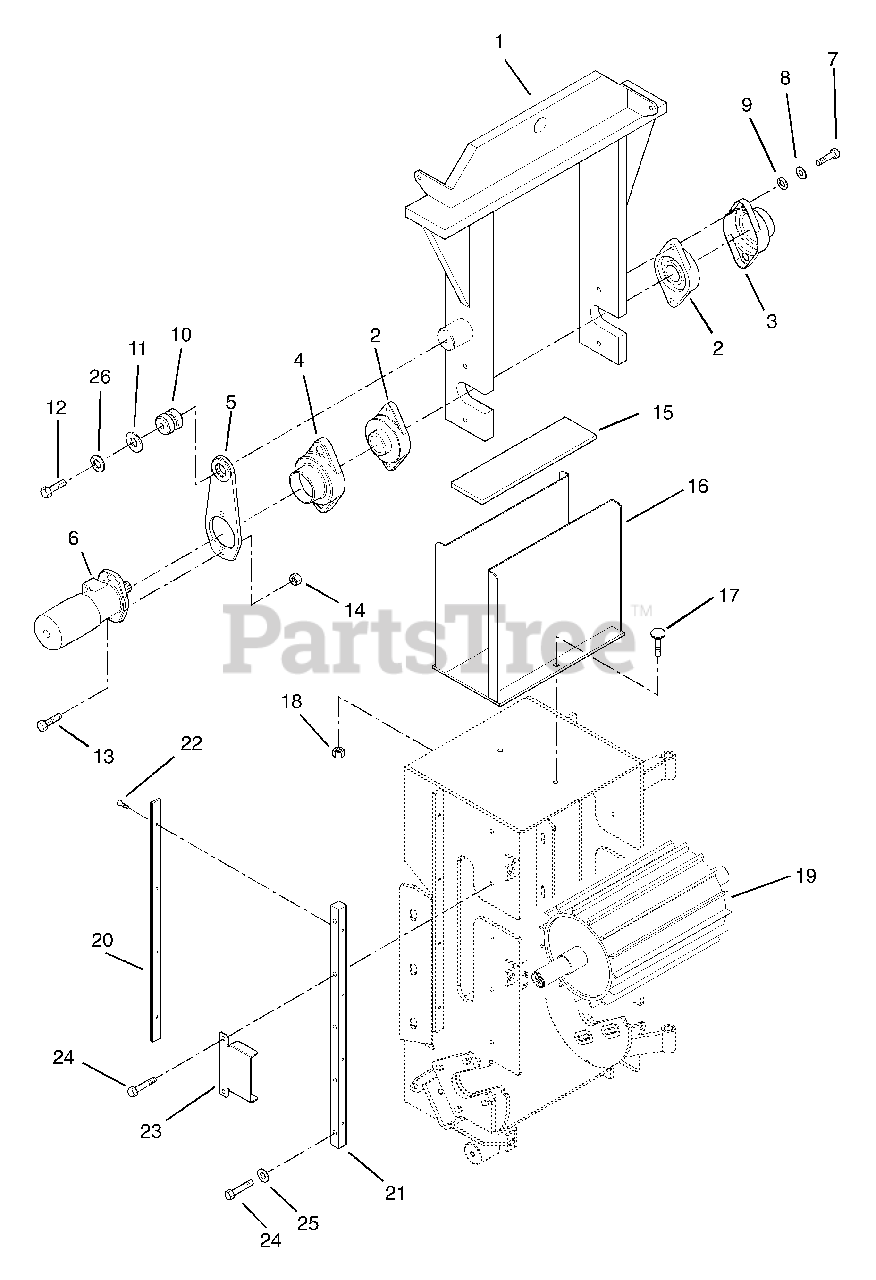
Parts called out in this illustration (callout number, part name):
1	Saddle Replacement
1	Saddle Weldment Assembly
3	Cover-Bearing
4	Cover-Shaft
5	Torque Arm Weldment
6	Hydraulic Motor
7	Bolt-Hex .50-13 x 1.25 Grade 5
8	Washer-Flat-Steel .531 x 1.06 x .095
9	Washer-Lock .50 x .125
10	Rubber Bushing
10	Bushing-Isolation
11	Washer-Flat-Steel .50 x 2.25 x .13
11	Washer-Flat-Steel .656 x 2.52 x .184
12	Bolt-Hex .50-13 x 3.00 Grade 5
12	Bolt-Hex .625-11 x 4.00 Grade 8
13	Bolt-Hex .50-13 x 1.50 Grade 5
14	Nut-Locking-Center .50-13
15	Rubber Stop
16	Saddle Guard Weldment
17	Bolt-Round Head Square Neck .38-16 x 1.00
18	Nut-Lock-Center .38-16
19	Roller-Top Weldment
20	Wear Strip
21	Front Guide
22	Screw-Machine .25-20 x .50
23	Feed Box Guard
24	Bolt-Hex .38-16 x 1.50 Grade 5
25	Washer-Flat-Steel .438 x 1.00 x .083
26	Washer-Locking .50 x .125
26	Washer-Locking .62 x .156
